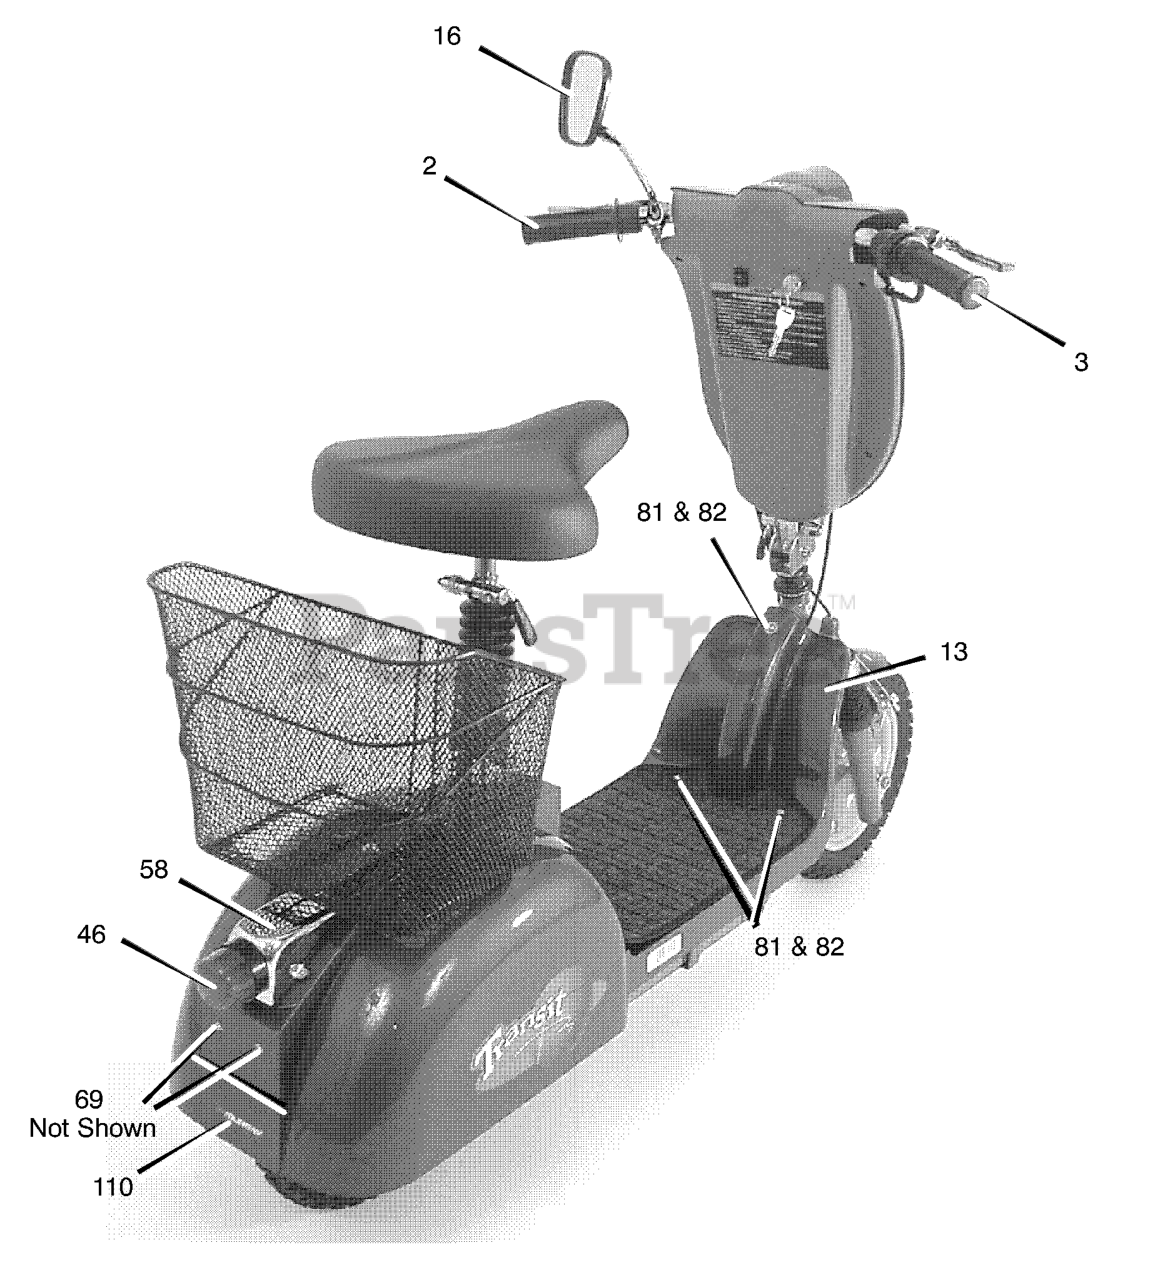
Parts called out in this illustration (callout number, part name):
2	Grip, Left
3	Grip, Right (for Throttle)
13	Footrest, Frame
16	Mirror, Rear view-w/ Hardware
46	Light Ass'y, Rear (w/harness)
58	Bracket, Tail Light Mount
69	Bracket, License Plate
110	Decal, Murray
